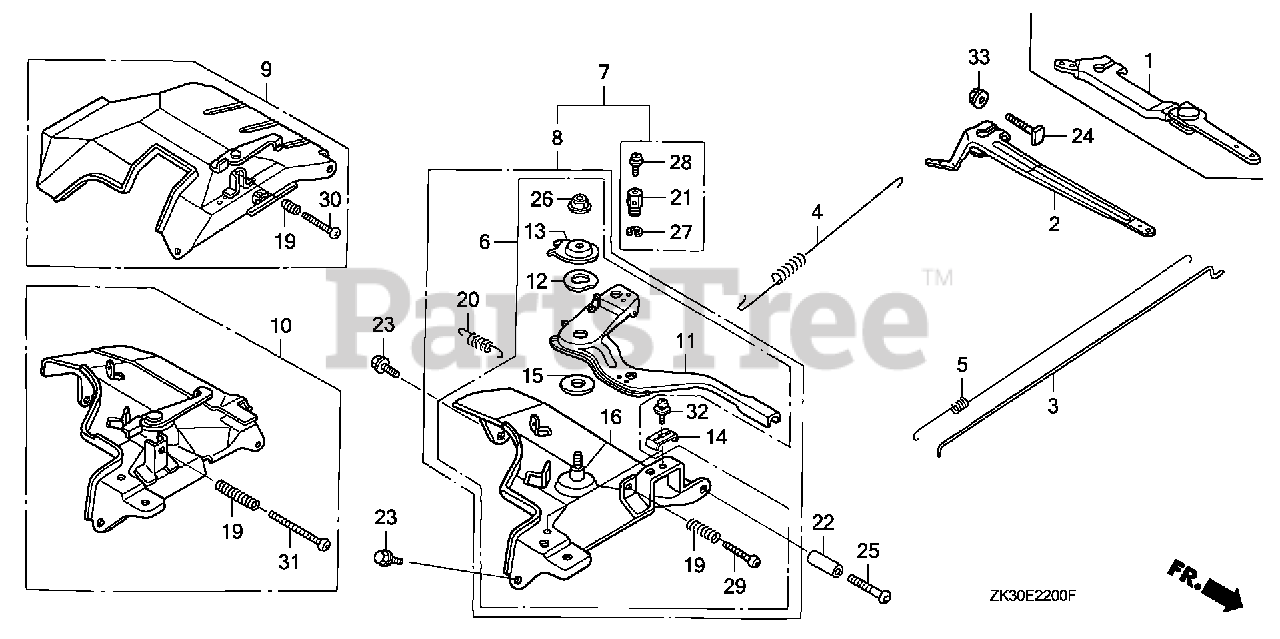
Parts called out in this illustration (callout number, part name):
1	ARM, GOVERNOR
3	ROD, GOVERNOR
4	SPRING, GOVERNOR (L=137.5MM)
5	SPRING, THROTTLE RETURN
9	CONTROL ASSY.
19	SPRING, CONTROL ADJUSTING
23	BOLT, FLANGE (6X12) (CT200)
24	BOLT, GOVERNOR ARM
30	SCREW, PAN (5X35)
33	NUT, FLANGE (6MM)
